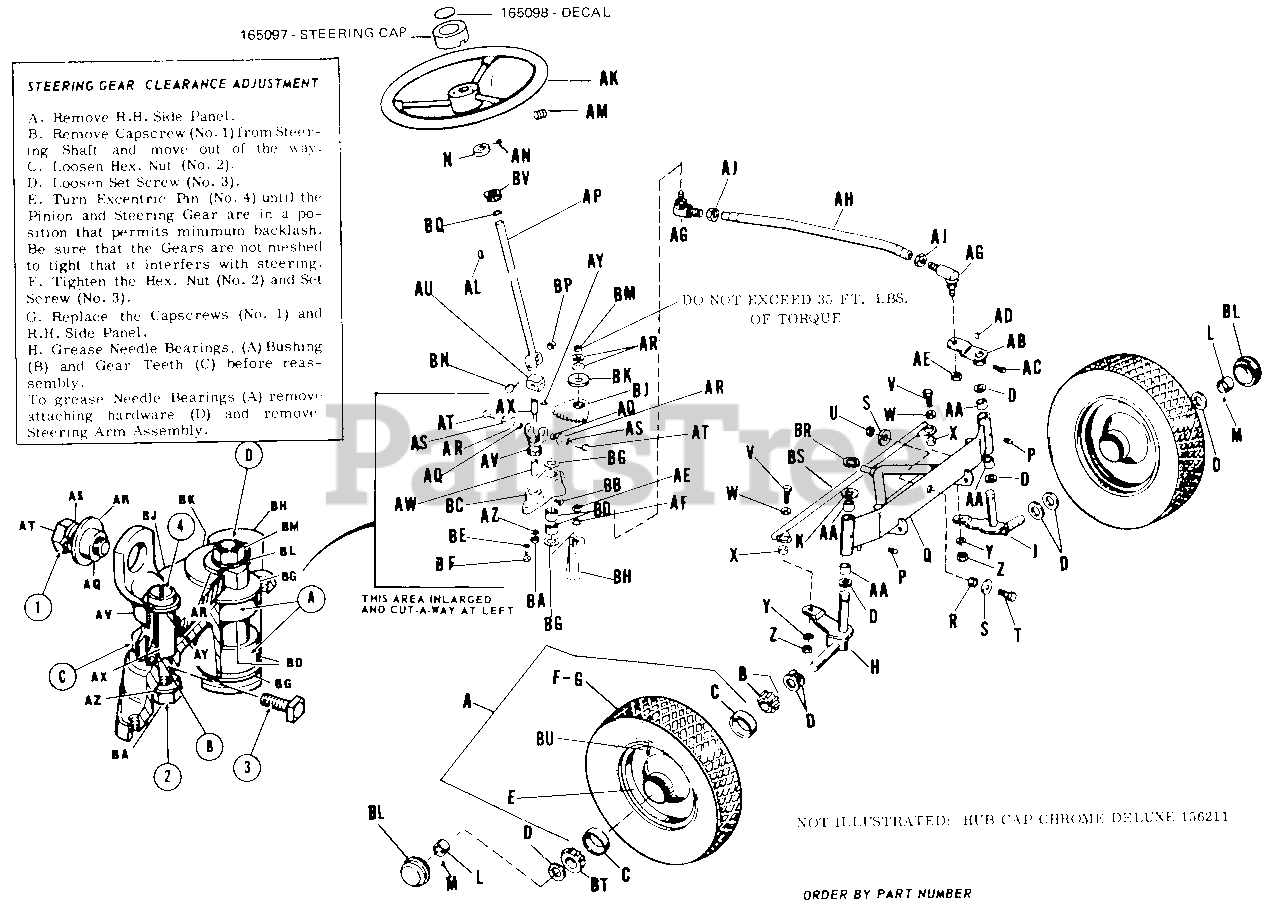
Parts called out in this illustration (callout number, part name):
A	Wheel and Tire Assembly
B	Bearing Cone, w/seal
C	Bearing Cup
E	Wheel w/Bearing Cup
H	Spindle Assembly R.H.
J	Spindle Assembly L.H.
L	Set Collar
M	Cup Point Socket Head Set Screw, 5/16"-18 x 5/16" lg.
N	Set Collar
P	Grease Fitting
Q	Axle Assembly, Front
S	Plain Washer, 1/2"
T	Hex. Cap Screw, 1/2"-13 x 1" lg.
U	Full Lock Hex. Nut, 1/2"-13
V	Hex, Cap Screw, 3/8"-16 x 1-1/4" lg.
W	Plain Washer, 3/8"
Y	Lock Washer, 3/8"
Z	Full Hex. Nut, 3/8"-16
AB	Arm Assembly, Steering, L.H.
AC	Screw set Cup point, Square Head, 5/16"-18 x 1/2" lg.
AE	Full Hex. Lock Nut 1/2"-20
AF	Lock Washer, 1/2"
AJ	Nut, 1/2"-20
AK	Steering Wheel
AL	Woodruff Key, #9
AM	Socket Head Cup Point Set Sc rew, 5/16"-18 x 5/16" lg.
AN	Steering Hd. Set Screw, 5/16"-18 x 1/4" lg.
AP	Steering Shaft Assembly
AR	Plain Washer, 3/8"
AS	Lock Washer, 3/8"
AT	Hex Cap Screw, 3/8"-16 x 3/4" lg
AU	Universal Joint Pin
AV	Bushing Assembly
AX	Pin Eccentric
AY	Retainer Ring
AZ	Lock Washer
BA	Full Hex. Nut, 3/8"-16
BB	Sq. Hd. Set Screw, 1/4"-20 x 3/4" lg.
BC	Steering Bracket
BD	Needle Bearing
BE	Lock Washer, 5/16"
BF	Hex. Cap Screw, 5/16"-18 x 5/8"
BH	Steering Arm Assembly
BJ	Gear Steering
BK	Arbor Washer
BL	Hub Cap
BM	Gripco Center Lock 7/16"-14
BN	Hex Cap Screw,
BP	Full Hex. Nut, 5/16"-18
BR	Retaining Ring
BS	Drag Link
BT	Outside Bearing
BU	Valve Stem
BV	Steering Bushing
